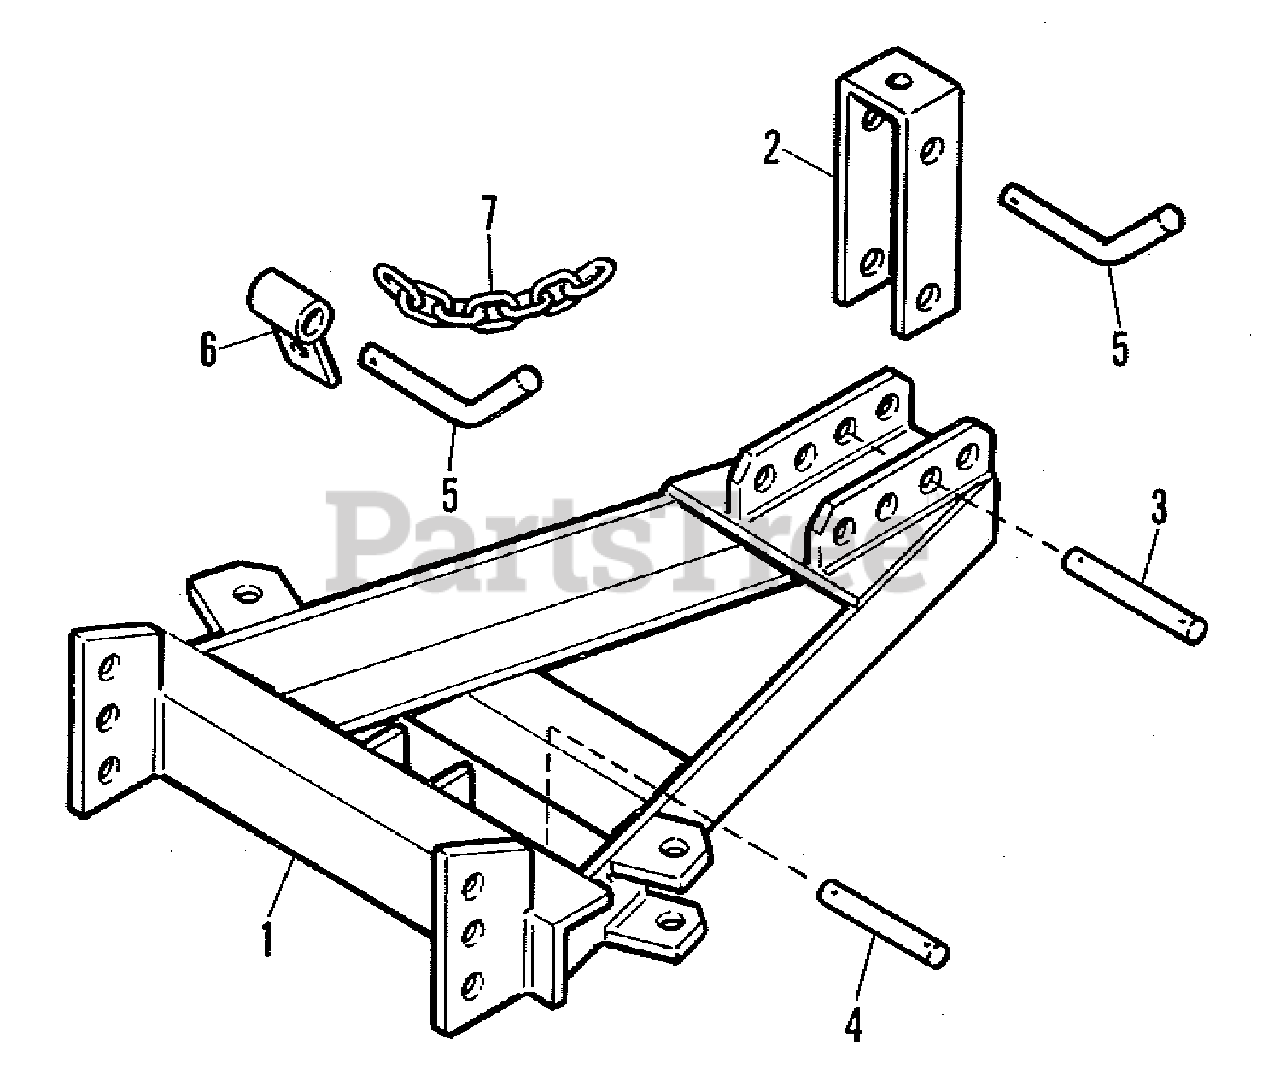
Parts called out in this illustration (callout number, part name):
1	FRAME ASSEMBLY
1	CAPSCREW, 3/4NC x 2
1	NUT, Lock, 3/4NC
2	ARM, Chain Lift
2	CAPSCREW, 7/16NC x 2
2	WASHER, Plain, 15/32 x 1 x 14 Ga.
2	LOCKWASHER, 7/16
2	NUT, 7/16NC
3	PIN, Chain, Lift Arm
3	PIN, Cotter, 3/16 x 2
4	PIN, Straight, Lift Cylinder
4	PIN, Cotter, 3/16 x 2
5	PIN, Pistol Grip, Lift Cylinder
5	CLIP, Hairpin
6	ADAPTER, Chain Lift, Upper
6	CAPSCREW, 7/16NC x 2
6	WASHER, Plain, 15/32 x 1 x 14 Ga.
6	LOCKWASHER, 7/16
6	NUT, 7/16NC
7	CHAIN, Lift
